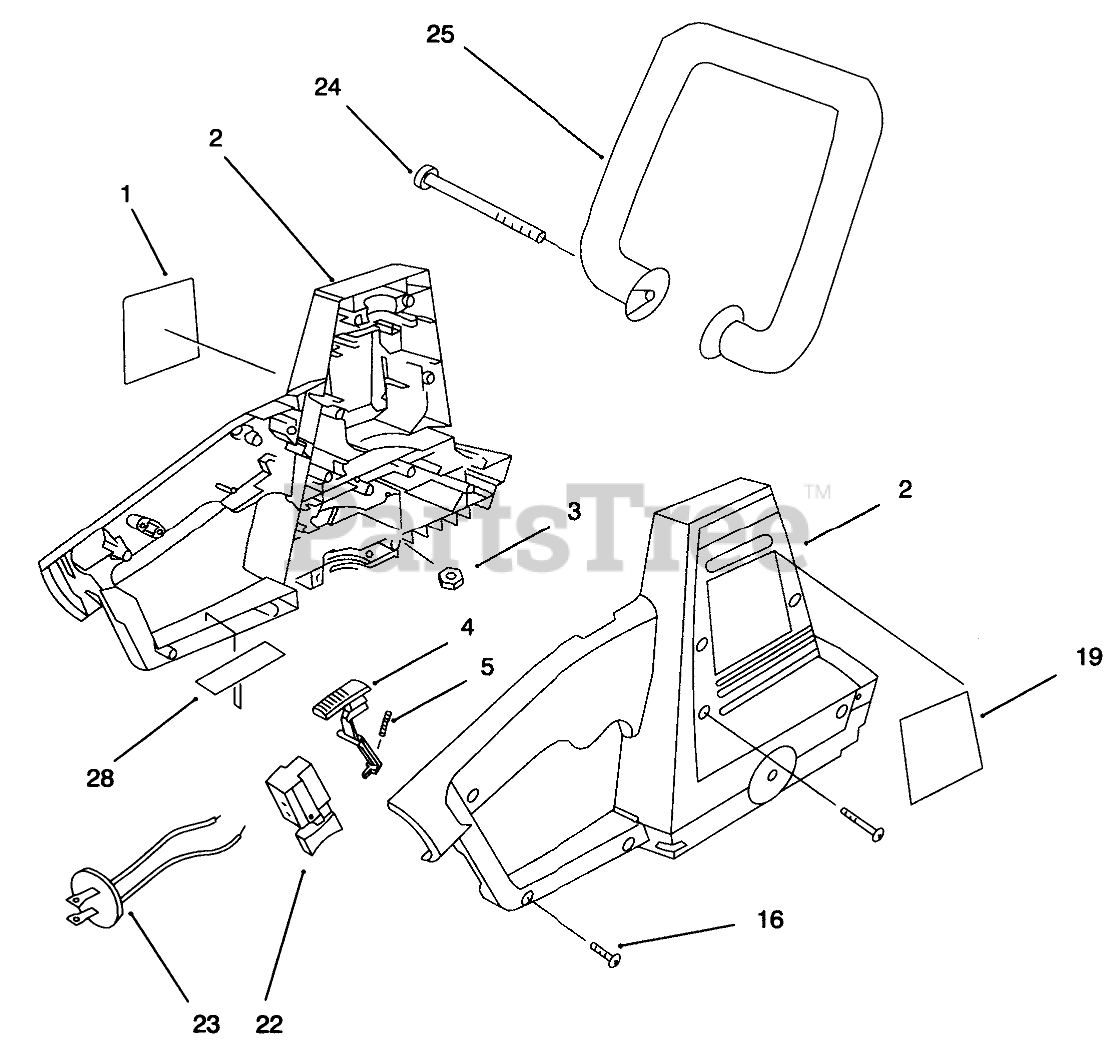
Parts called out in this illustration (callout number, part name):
1	PLATE - LOGO
2	ASSEMBLY - HOUSING
3	NUT - HEX #8-32
4	BUTTON - LOCK-OFF
5	SPRING
16	SCREW
19	LABEL - WARNING
22	SWITCH
23	ASSEMBLY - DISC
24	SCREW
25	HANDLE - FRONT
28	PLATE - DATA
